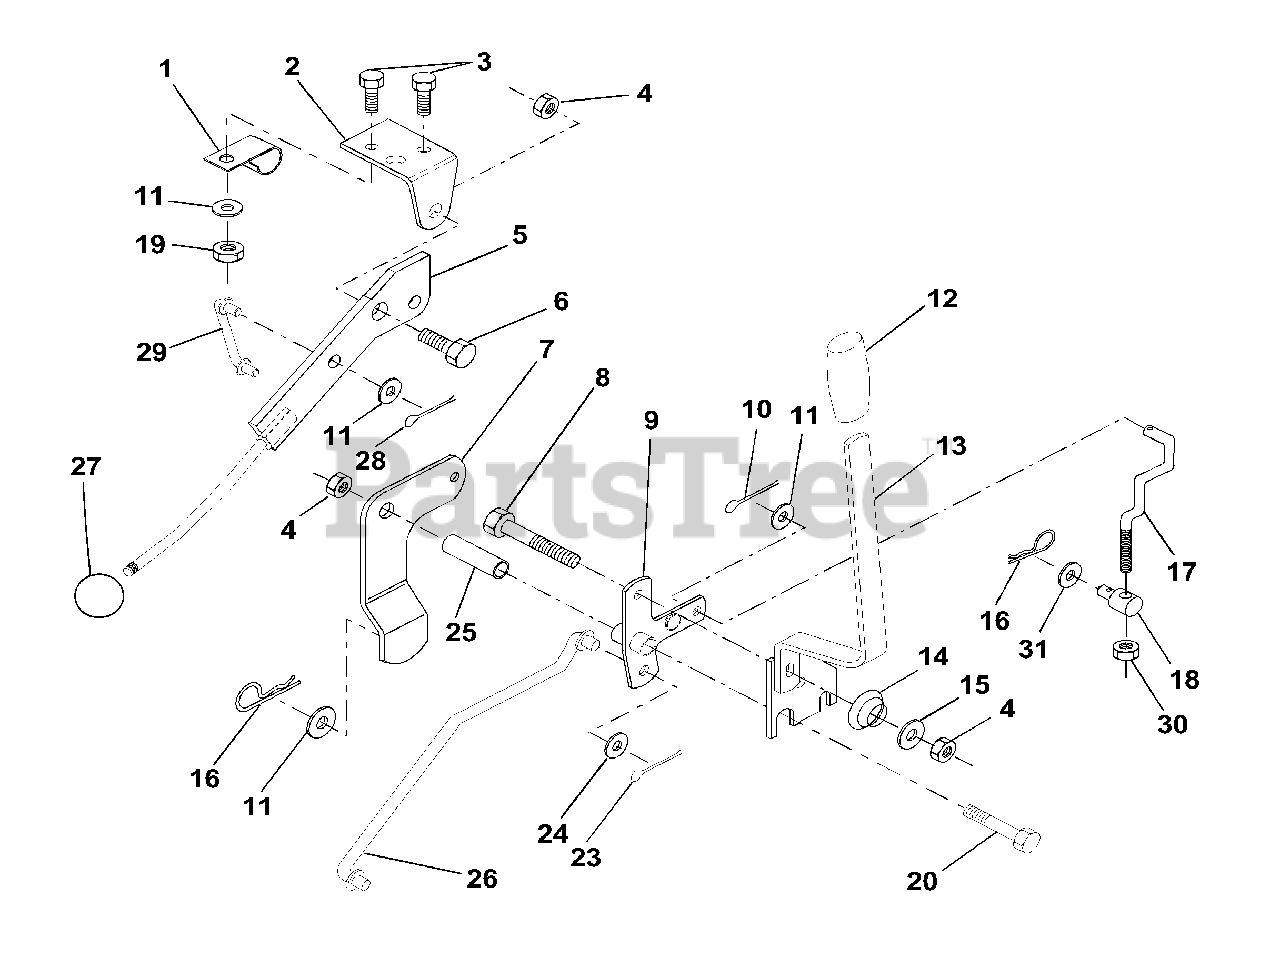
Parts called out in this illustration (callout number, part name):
1	Clip, Insulated
2	Bracket, Mower Clutch
3	Bolt, Fin. Hex 1/4-20 UNC x 1/2
4	Nut, Crownlock 3/8-16 UNC
5	Assembly, Clutch Lever
6	Bolt, Shoulder
7	Assembly, Mower Clutch Arm
8	Bolt, Hex 3/8-16 UNC x 2-1/4
9	Bellcrank, Asm. Lift
10	Pin, Cotter 1/8 x 3/4
11	Washer 13/32 x 13/16 x 16 Ga.
12	Grip, Handle
13	Assembly, Lift Handle
14	Spring, Compression
15	Washer 13/32 x 3/4 x 12 Ga.
16	Retainer, Spring
17	Link, Front Lift
18	Trunnion, Adj. 94
19	Nut, Crownlock 1/4-20
20	Bolt, Fin. Hex 3/8-16 UNC x 2-3/4
23	Pin, Cotter 1/8 x 1
24	Washer 17/32 x 1 x 16 Ga.
25	Tube, Spacer
26	Rod, Mower Lift
28	Pin, Cotter 3/32 x 3/4
29	Link, Mower Clutch
30	Nut Hex Jam 3/8-16 Unc
31	Washer 13/32 x 1-1/4 x 12
